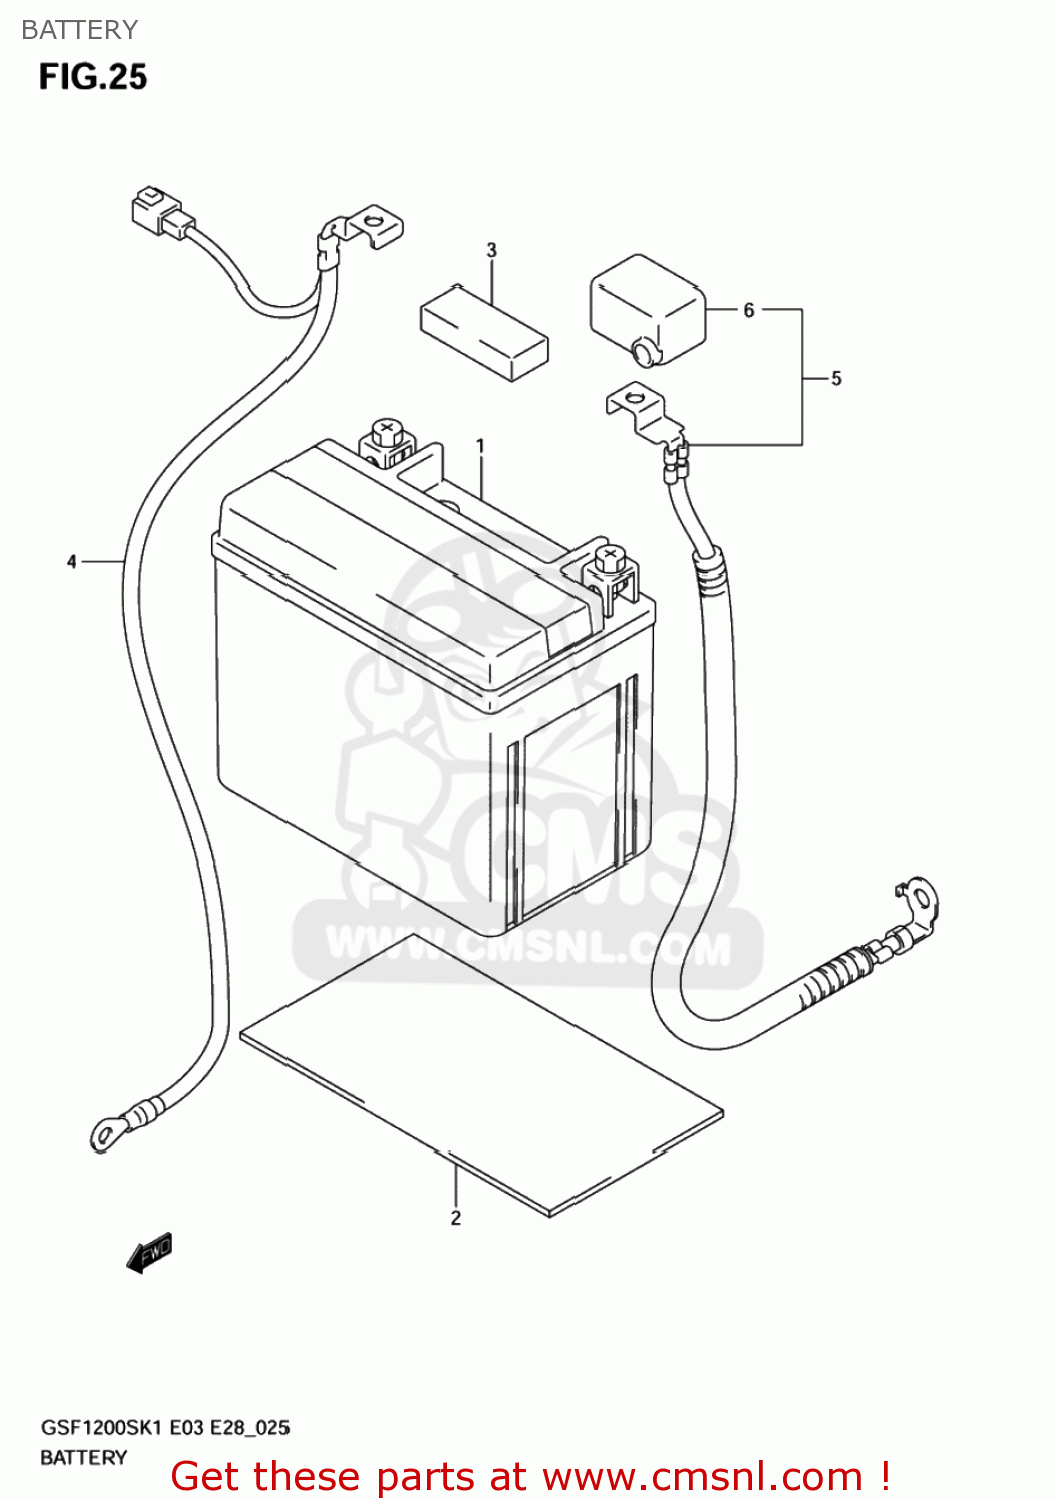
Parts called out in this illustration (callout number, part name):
1	BATTERY ASSY(YTX12-BS,12V10AH)
2	PROTECTOR(170X95X3.0)
3	PROTECTOR(20X50X11)
4	WIRE,BATTERY MINUS LEAD
5	WIRE,BATTERY PLUS LEAD
6	CAP,BATTERY PLUS
